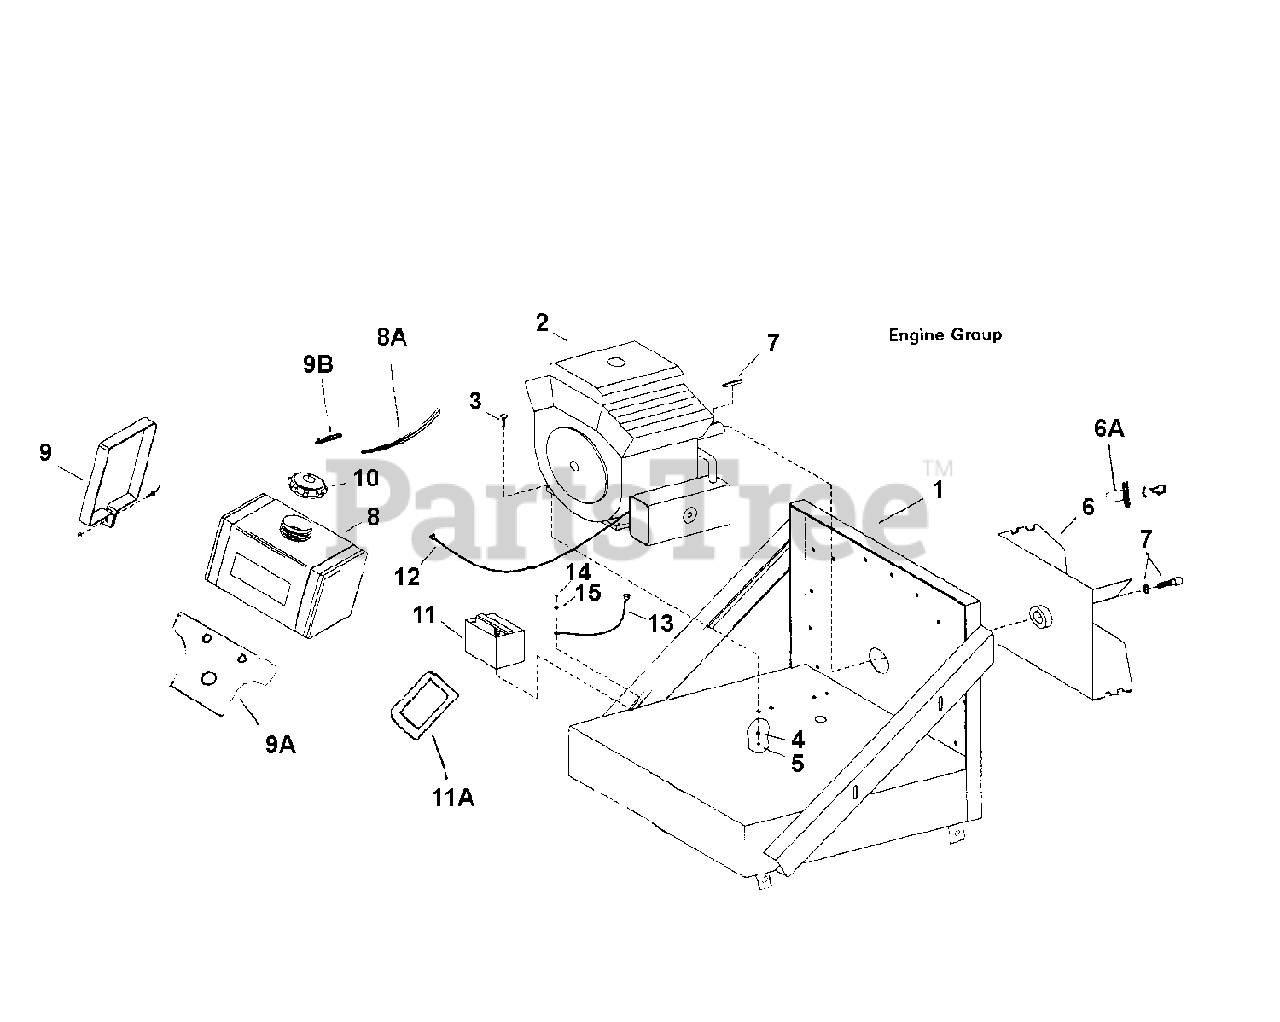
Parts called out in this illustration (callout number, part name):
1	Engine Base
2	* 20HP Kohler Command Engine
3	3/8-16x1-3/4 Hex Bolt
4	3/8 Lock Washer
5	3/8-16 Hex Nut
6A	Impeller Hub
7	Kit, Key and Bolt
8	Fuel Tank
8A	Hose, Rubber Fuel 1/4 inch
9	Fuel Tank Strap
9A	Fuel Tank Mount
9B	In-Line Fuel Valve
10	Fuel Tank Cap (Part of Tank)
11A	Battery Box
12	Battery Cable - 32SS (Positive)
13	Battery Cable - 16SS (Ground)
